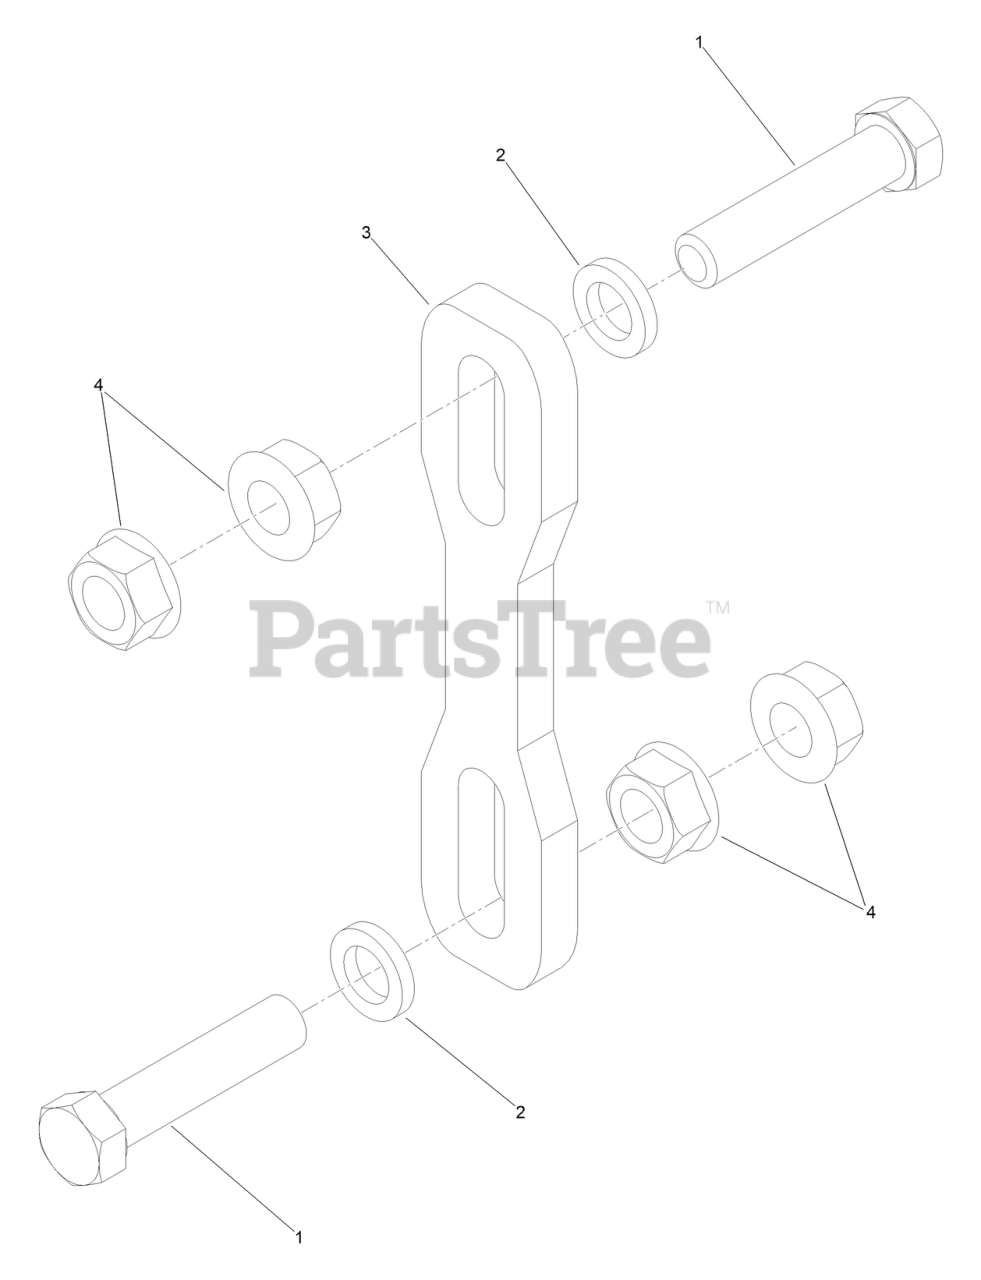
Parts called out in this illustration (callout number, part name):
1	MWR DECK SUSP LINK PAINT
2	SCREW-HH
3	.443 ID X .749 OD X .125 THK NYLON BLACK
4	NUT-HF
